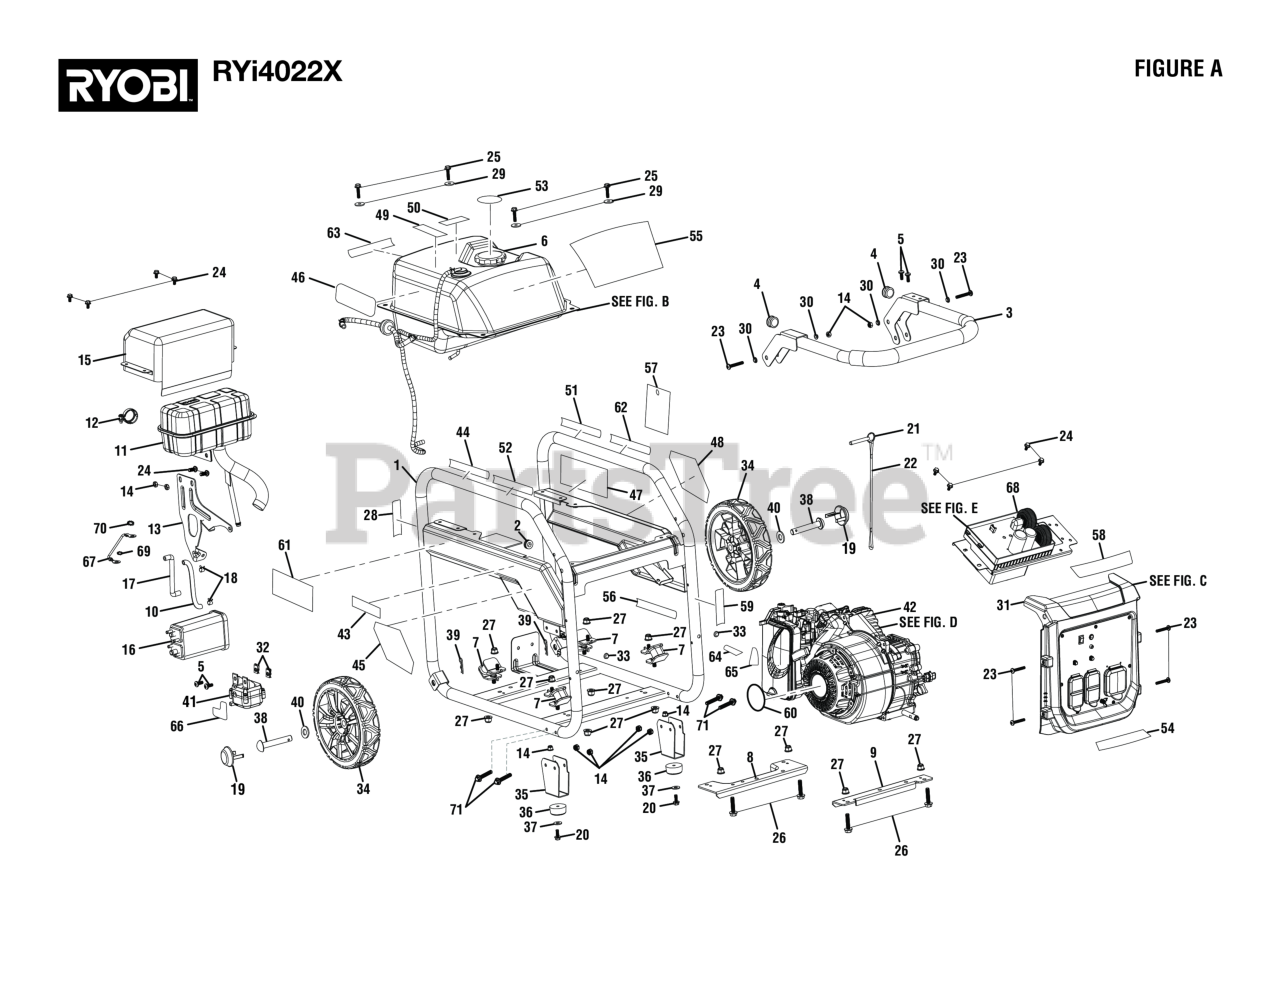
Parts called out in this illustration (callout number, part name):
1	Frame Assembly
2	Grommet
4	Handle End Caps
5	Bolt (M6 x 10 mm, T30 Torx Pan Hd.)
6	Fuel Tank Assembly
7	Isolator (45 Deg)
8	Bottom Plate (Left)
9	Bottom Plate (Right)
10	Pair Valve Hose
12	Spark Screen
13	Muffler Bracket
14	Lock Nut (M6 x 1 mm)
15	Muffler Heat Shield
16	Carbon Canister (Rewin Q-08-007 RW320cc)
16	Carbon Canister (Depurate Q-13-004)
17	Carbon Canister To Airbox Hose.
18	Fuel Line Clamp (3/8 in.)
20	Bolt (M6 x 16 mm, Hex Hd)
21	Release Pin (5/16 x 2 in.)
22	Lanyard (3/16 in.)
23	Bolt (M6 x 40 mm, T30 Torx Pan Hd.)
24	Flange Bolt (M6 x 12 mm)
25	Flange Bolt (M6 x 25 mm
26	Flange Bolt (M6 x 16 mm, T30 Torx Pan Hd.)
27	Lock Nut (M8 x 1.25 mm, Flange)
28	Hot Surface Label
30	Shoulder Washer
31	Control Panel Assembly
32	U-Clip (M6)
33	Handle Bumper
34	Front Wheel Assembly
36	Rubber Wear Pad
37	Washer (1/4 in.)
39	Hitch Pin
40	Washer (1/2 in.)
41	Control Module Assembly
43	Inquires Label (Ryobi)
44	Combustion Label
45	Monitoring System Label
46	Co Instruction & Warning Label
47	CPSC Danger Label
48	Danger Icon Label
49	No E85 Label
50	Exhaust Direction Label
51	Fire Distance Label (Eng/Sp)
52	Risk of Fire Danger Label
53	Remove Cap Fuel Stabilizer Label (English)
54	Ground Warning Label (English/French)
55	Tank Logo Label
56	Engine Lubricant Label
57	Warning Hangtag
58	Performance Label
59	Locking Pin Label
60	Engine Recoil Label
61	Start Label
62	Fuel Stabilizer Label (Fr/Sp)
63	Hot Surface Label
64	Off Label
66	Led Warning Label
67	Ground Wire
68	Invert Module assembly
69	Washer (5/16 in., External Star)
70	Star Washer (ID6.4 x OD11 x 0.6t)
71	Bolt (M6 x 40 mm, Flange Hex Hd.)
